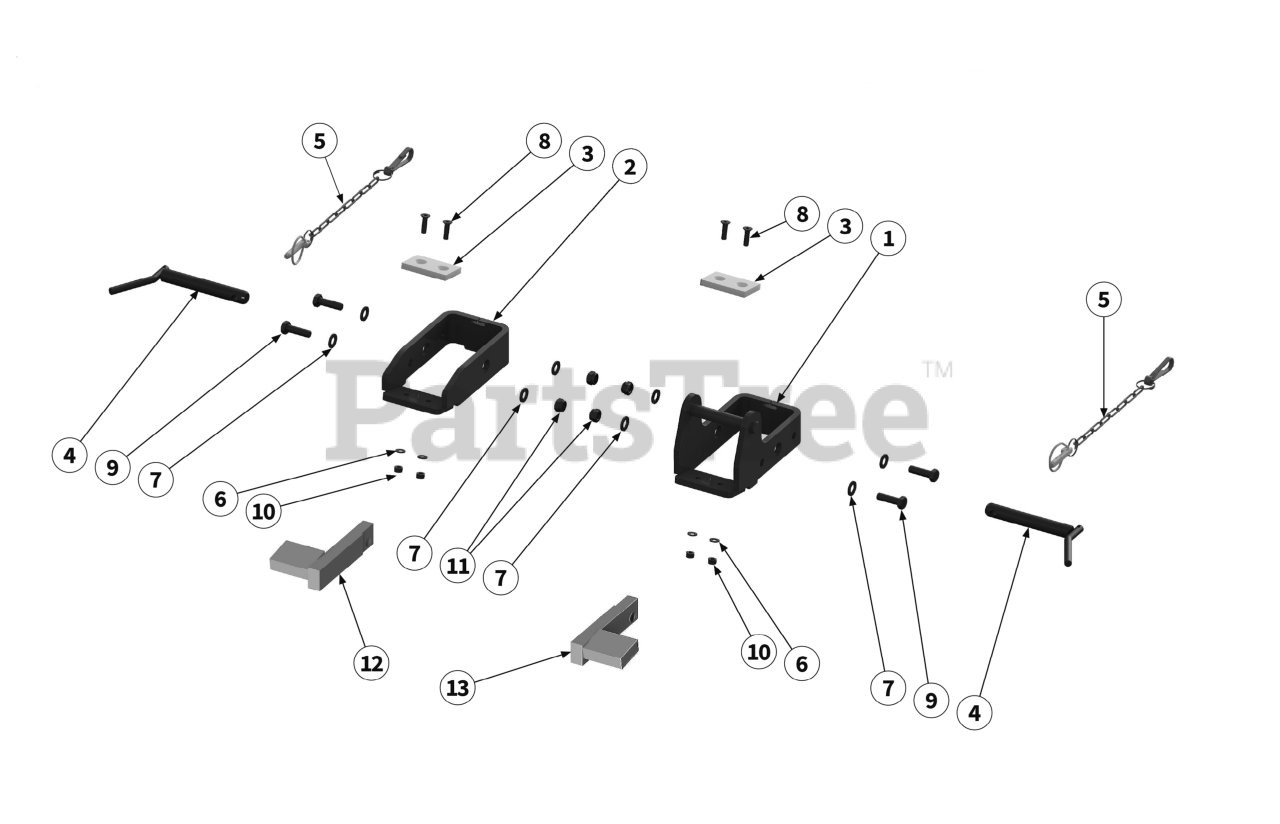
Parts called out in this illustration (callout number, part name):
1	MOUNTING BRACKET
2	MOUNTING BRACKET
3	PLATE SKID
4	PIN MOUNTING BRACKET
